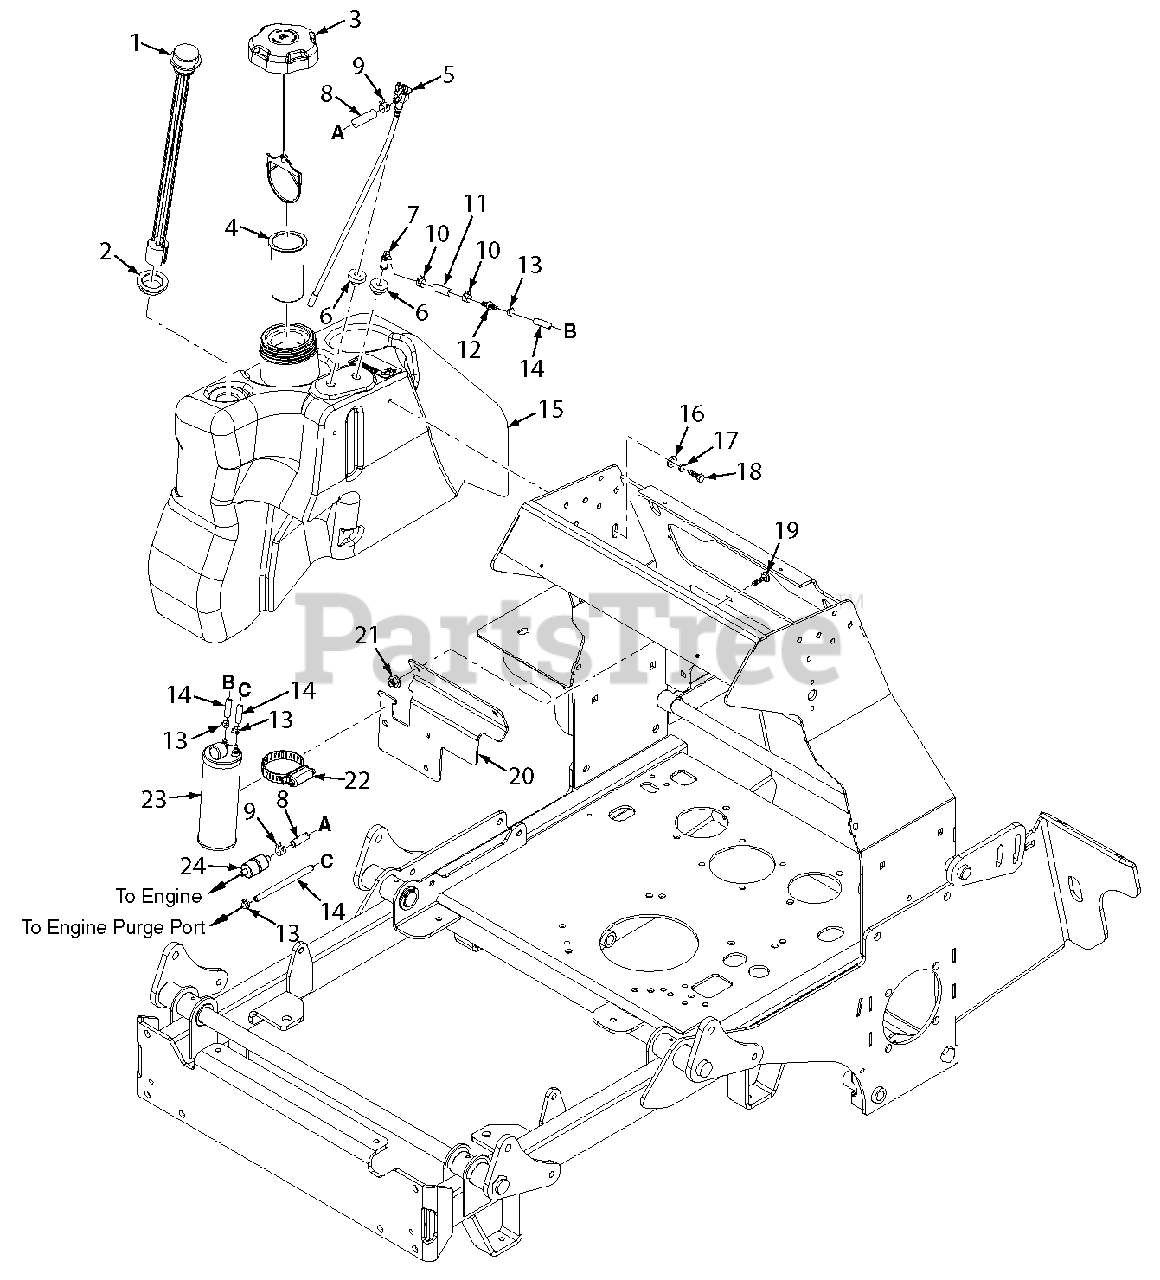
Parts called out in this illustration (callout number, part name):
1	Fuel Gauge Assy., 15-1/2" (36)
1	Fuel Gauge Assy., 16-1/2"
2	Seal, Fuel Gauge
3	Fuel Cap, Tethered
3	Fuel Cap, Tethered - CA models only
4	Tube, Fuel Tank Insert
5	Valve, Fuel Shutoff (36)
5	Valve, Fuel Shutoff
6	Bushing, .56 Viton
7	Remote Vent
8	Fuel Hose, 1/4" ID (order by inch)
9	Clamp, Fuel Hose
10	Clamp, Fuel Hose 7/32" ID
11	Hose, Vapor Recovery 1/4" (order by inch)
12	Mender, 1/4 x 3/16 w/.02 Hole
13	Clamp, Vapor Recovery Hose 3/16"
14	Hose, Vapor Recovery 3/16"
15	Fuel Tank Assy., SVRII-36
15	Fuel Tank Assy., SVRII
16	Flatwasher, 5/16-.375 x .875 x .083
17	Lockwasher, 5/16"
18	Bolt, Hex Head 5/16-18 x 3/4"
19	Bolt, Carriage 5/16-18 x 3/4"
20	Bracket, Hydro Tank Mounting
21	Nut, Serrated Flange 5/16-18
22	Clamp, 3-1/2"
23	Carbon Canister
24	Fuel Filter
